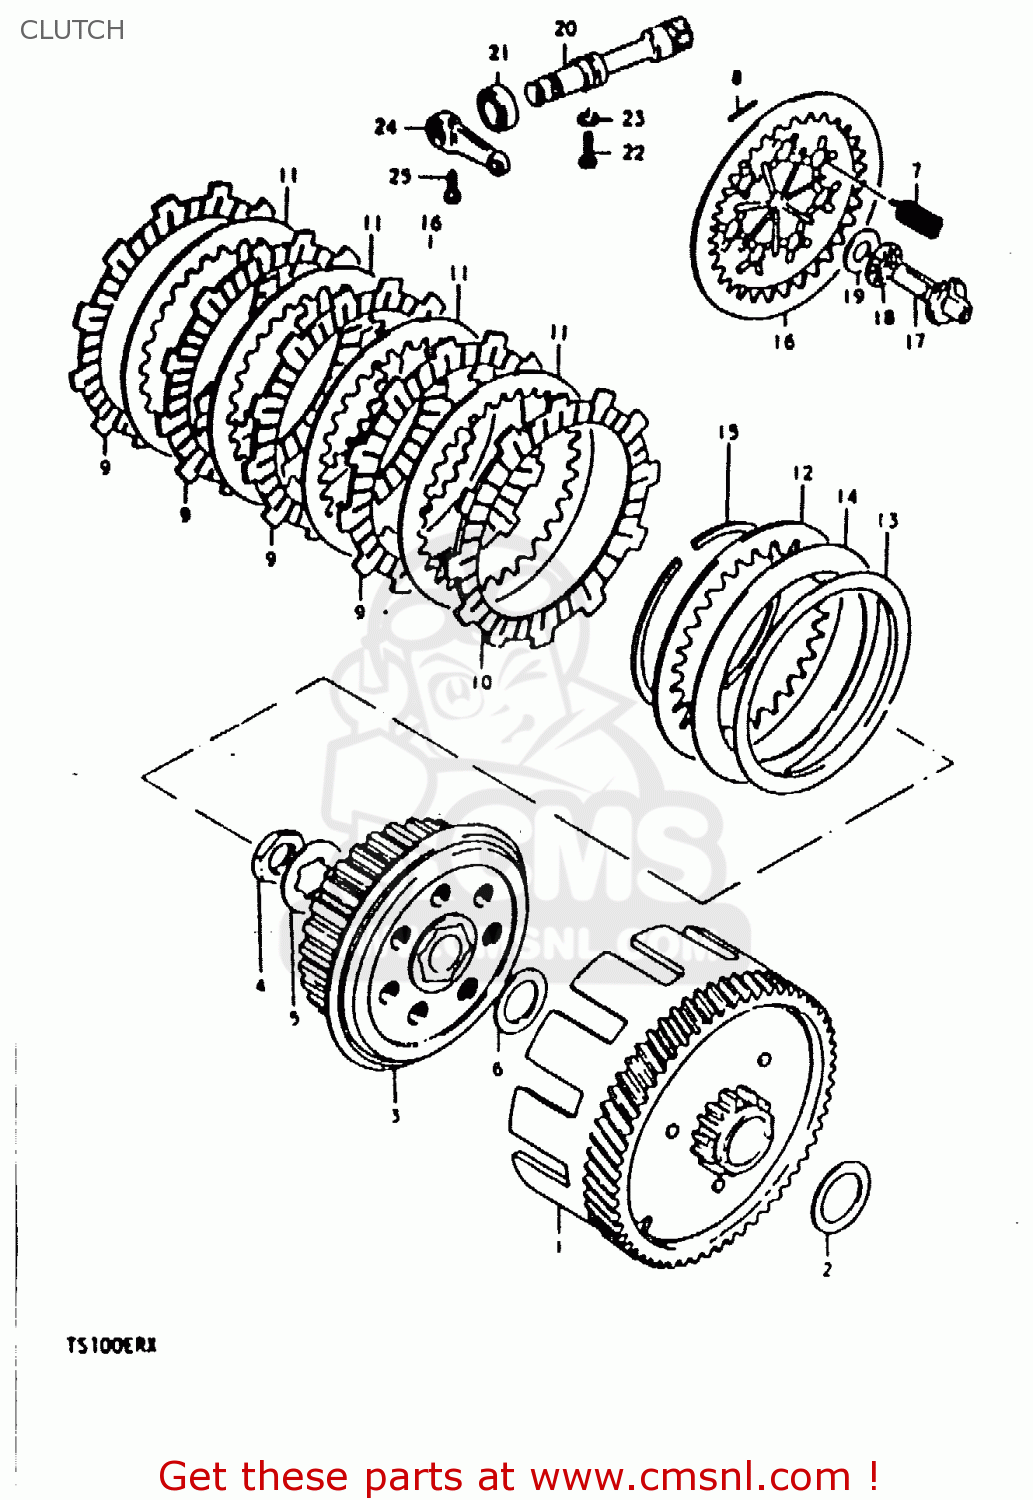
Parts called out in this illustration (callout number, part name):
1	GEAR ASSEMBLY,PRIMARY DRIVE
2	WASHER
3	HUB,CLUTCH SLEEVE
4	NUT
5	WASHER,LOCK
6	WASHER
7	SPRING
8	PIN(2.5X19.8)
9	PLATE,CLUTCH DRIVE
10	PLATE,CLUTCH DRIVE (MCA)
11	PLATE,CLUTCH DRIVEN (NAS)
12	PLATE,CLUTCH DRIVEN(T:2.0) (NAS)
13	SEAT,WAVE WASHER
14	WASHER
15	CIRCLIP
16	PLATE,CLUTCH PRESSURE
17	BACK,CLUTCH RELEASE
18	BEARING(10X22X2.8)
19	WASHER(10.1X21.4X0.8)
20	PINION,CLUTCH RELEASE
21	OIL SEAL
22	BOLT(6X12)
23	WASHER
24	ARM,CLUTCH RELEASE
25	BOLT
